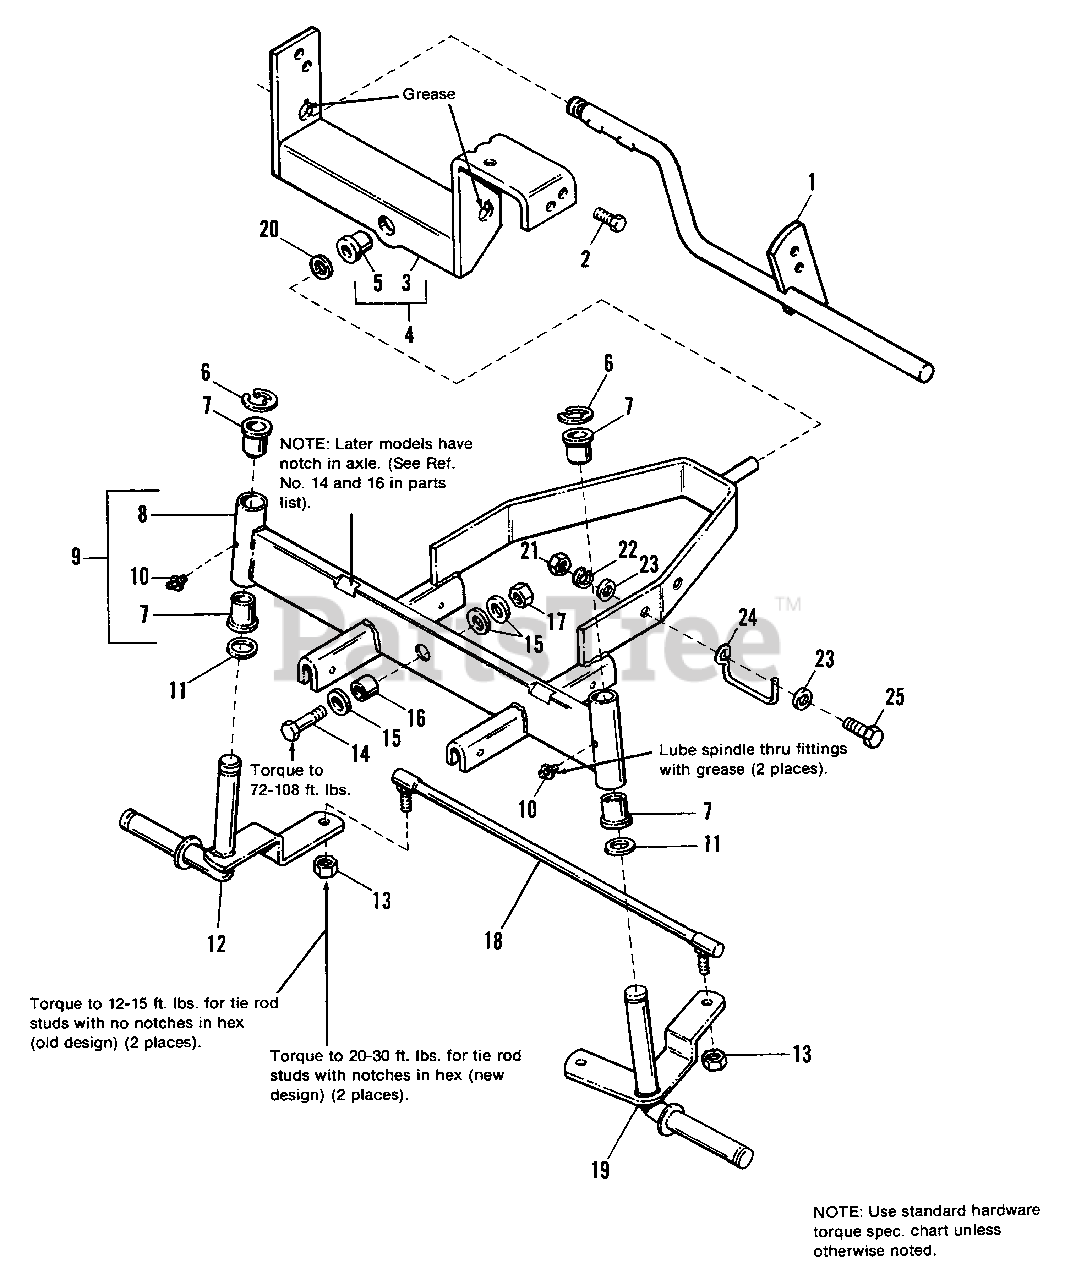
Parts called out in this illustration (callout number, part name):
1	LEVER ASSY., Brake
2	SCREW, Taptite, 5/16-18 x 3/4
4	SUPPORT ASSY., Rear w/Bushing
6	E-RING, Ext., 3/4
9	AXLE ASSY., Front
10	FITTING, Lube, 1/4-20
12	SPINDLE ASSY., R.H.
13	LOCKNUT, Hex, 3/8-24 (Gr. 8)
14	CAPSCREW, Hex, 1/2-13 x 1-3/4 (Gr. 8)
14	CAPSCREW, Hex, 1/2-13 x 1-1/2 (Gr. 8)
15	WASHER, 9/16
16	SPACER
17	LOCKNUT, Hex, 1/2-13
18	TIE ROD ASSY.
19	SPINDLE ASSY., L.H.
20	WASHER, 5/8
21	NUT, Hex, 5/16-18
22	LOCKWASHER, 5/16
23	WASHER, 5/16
24	GUIDE, Drag Link
25	CAPSCREW, Hex Hd., 5/16-18 x 1
